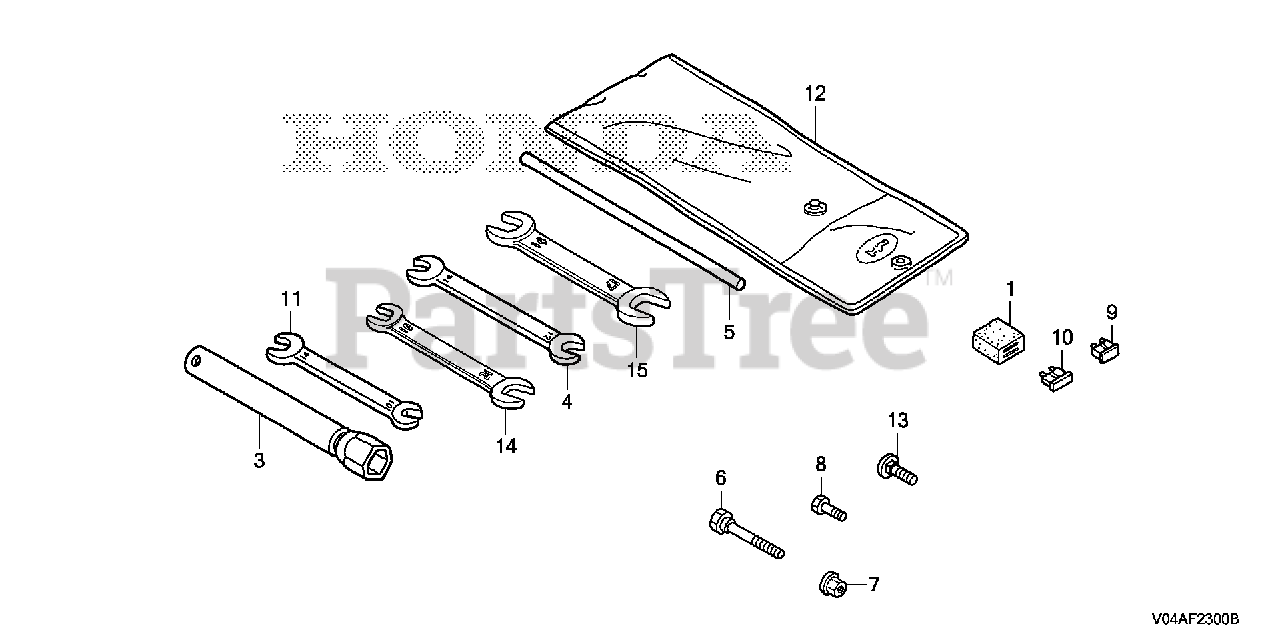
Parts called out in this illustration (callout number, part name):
3	WRENCH, SPARK PLUG
5	HANDLE, BOX WRENCH
7	NUT, SELF-LOCK (6MM)
8	BOLT, SPECIAL (6X18)
9	FUSE, BLADE (5A)
9	FUSE, MINI (5A)
13	BOLT, CARRIAGE (6X18)
14	SPANNER (10X12)
15	SPANNER (14X17)
